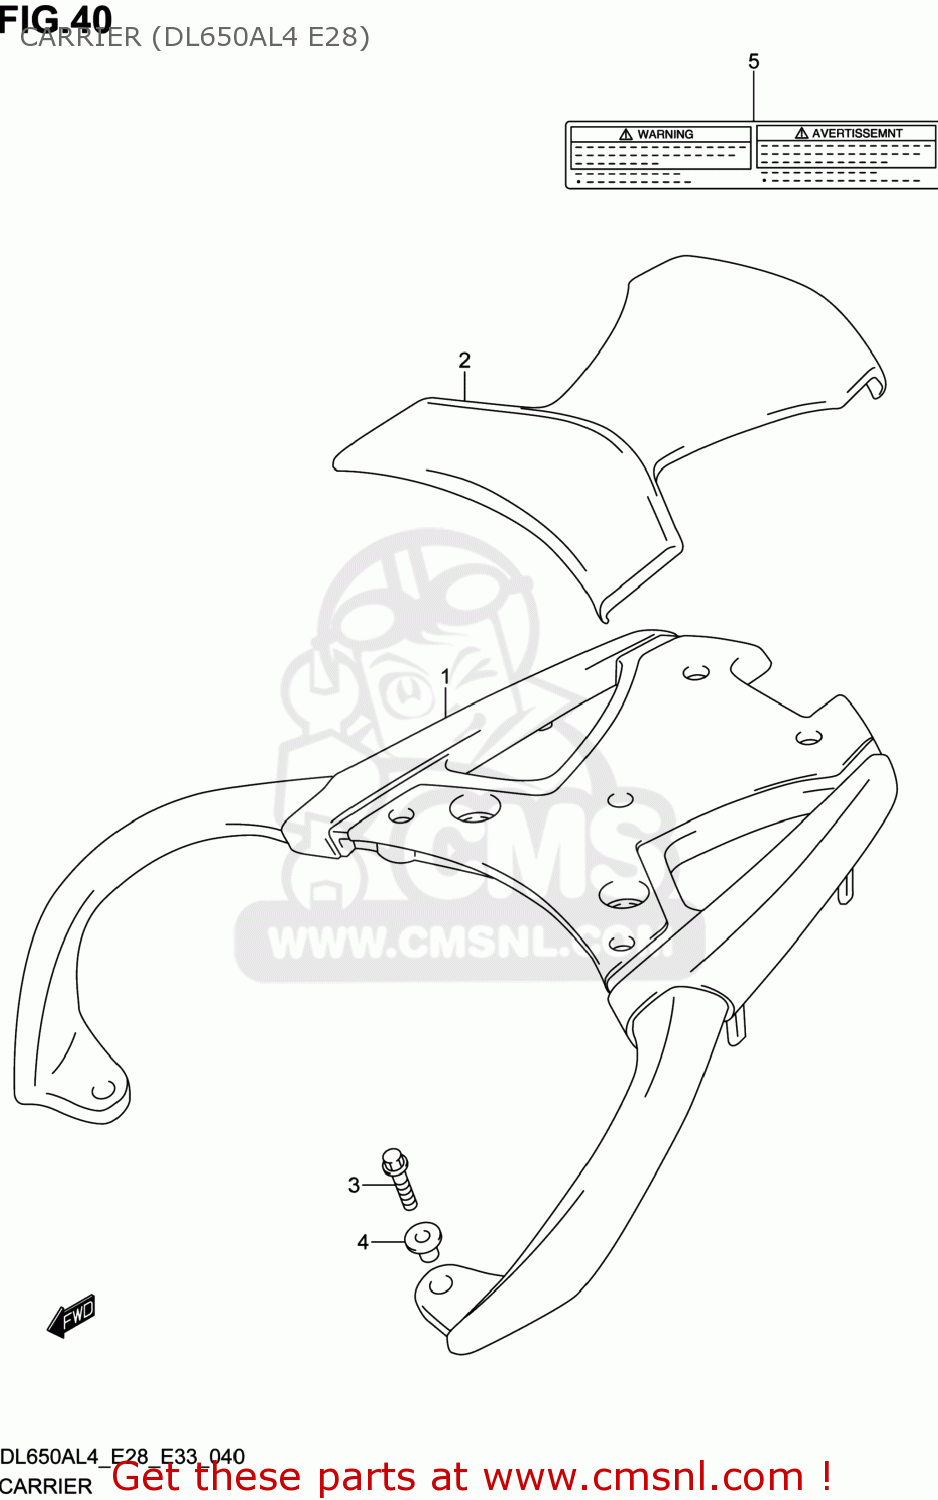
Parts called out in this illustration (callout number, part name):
1	CARRIER,SPORT
2	MAT,SPORT CARRIER
3	BOLT(8X35)
4	WASHER
5	LABEL,WARNING LUGGAGE CARRIER
